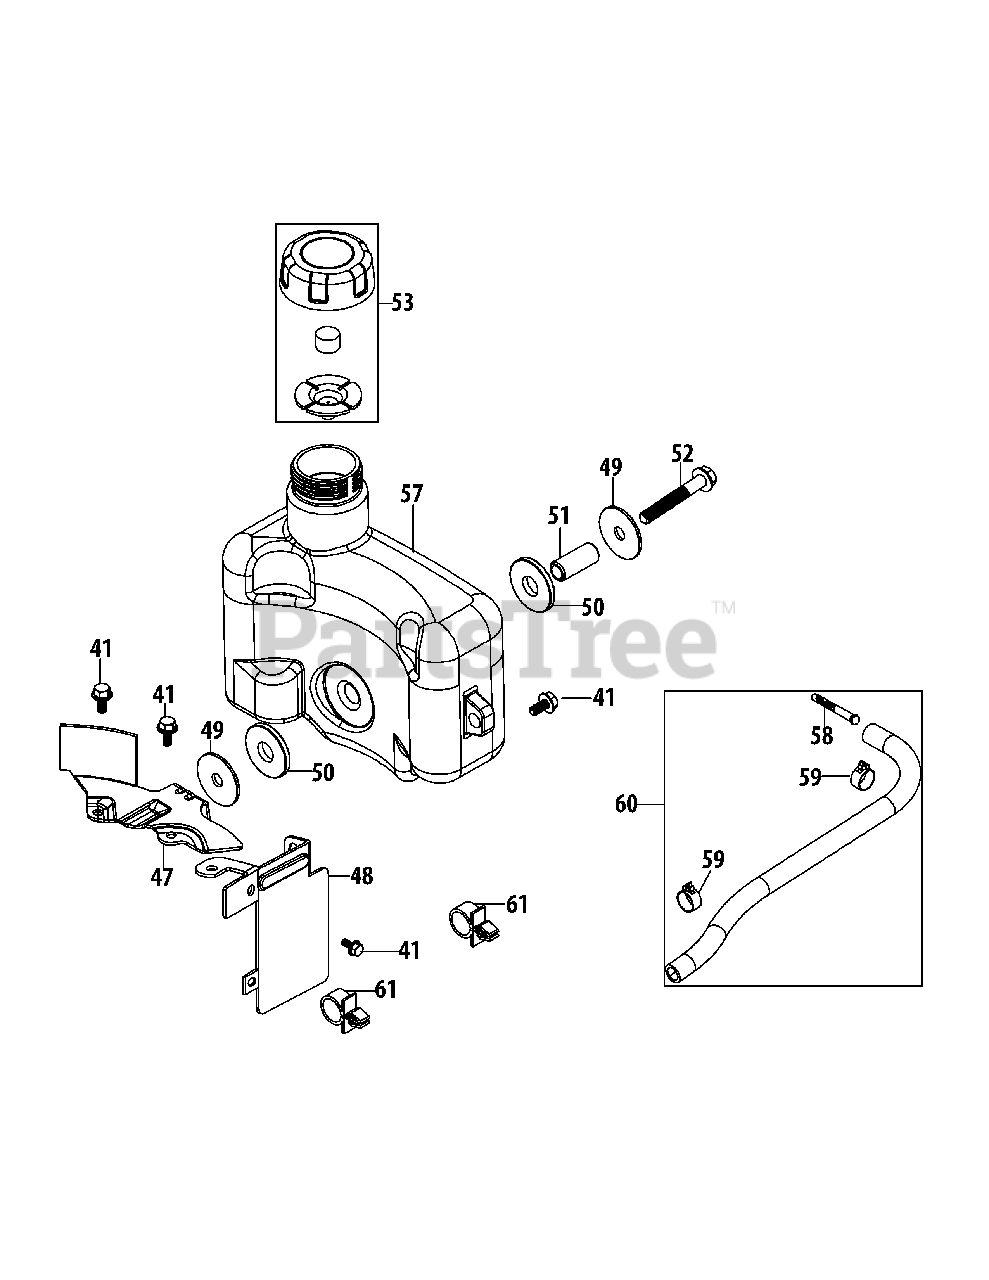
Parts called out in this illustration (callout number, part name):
41	Bolt M6X14
47	Fuel Tank Bottom Bracket
48	Fuel Tank / Label Bracket
49	Fuel Tank Washer
50	Rubber Bushing
51	Fuel Tank Bushing
52	Bolt M8X50 Fuel Tank
53	Fuel Cap Assembly
57	Fuel Tank Assembly
58	Fuel Filter
59	Fuel Hose Clamp
60	Fuel Line Kit
61	Plastic Support Clamp
